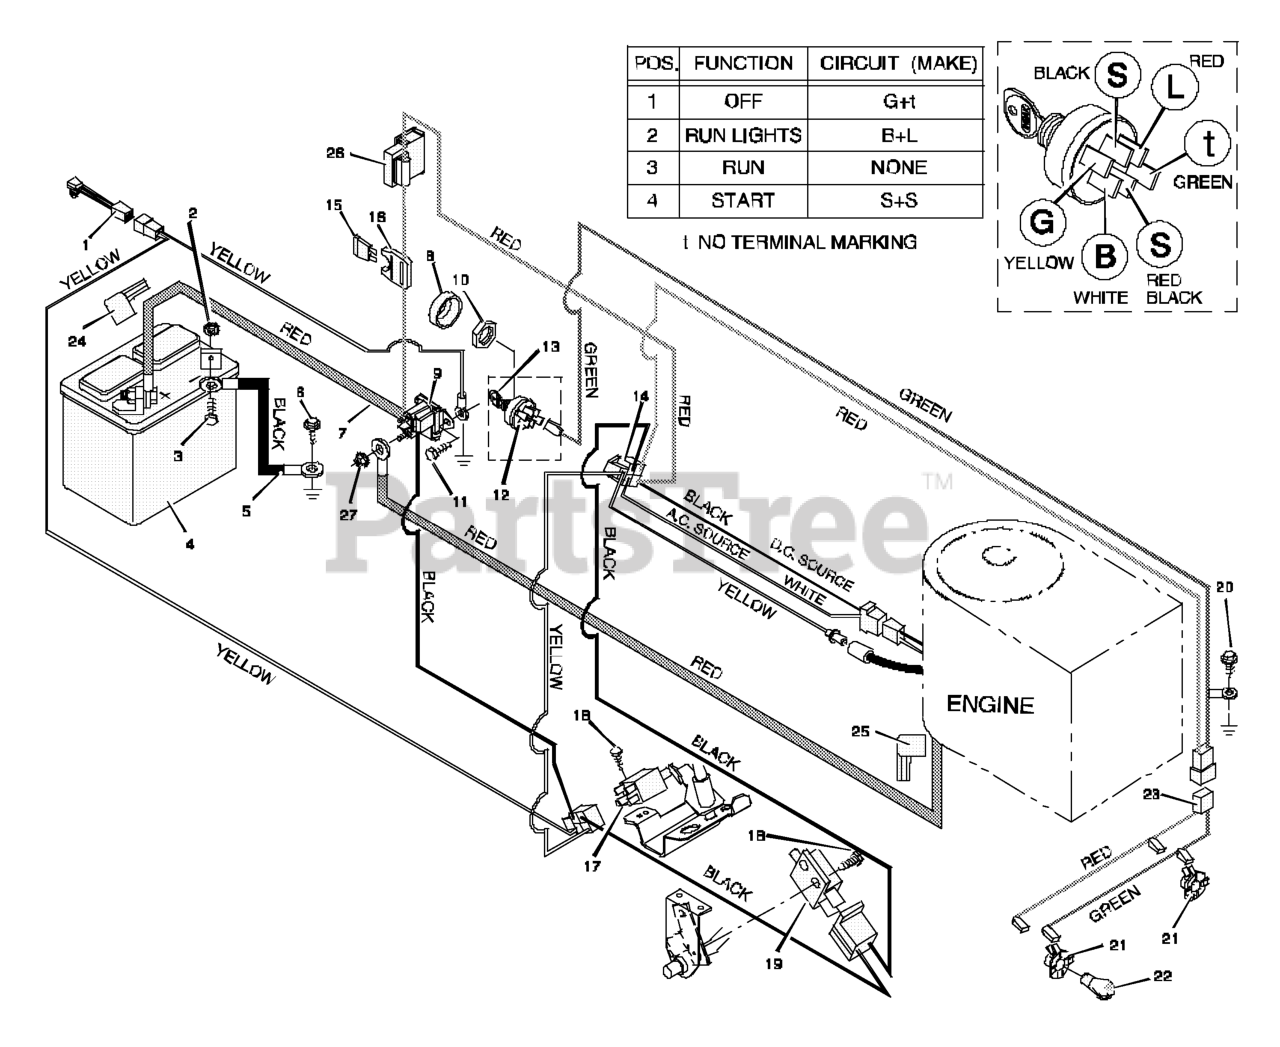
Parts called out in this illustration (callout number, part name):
1	Switch, Seat Sensor
2	Locknut
3	Bolt, Hex
4	Battery
5	Cable, Battery Ground
7	Cable, Red Battery
8	Cap, Ignition
9	Solenoid
10	Nut
12	Switch, Ignition
13	Key, Ignition
14	Harness, Chassis Wire
16	Holder, Fuse
17	Switch, Clutch
19	Switch, Clutch
20	Screw
21	Socket, Light
22	Bulb, Light
23	Harness, Light Wire
24	Cover, Terminal
25	Cover,
26	Ammeter
27	Locknut
